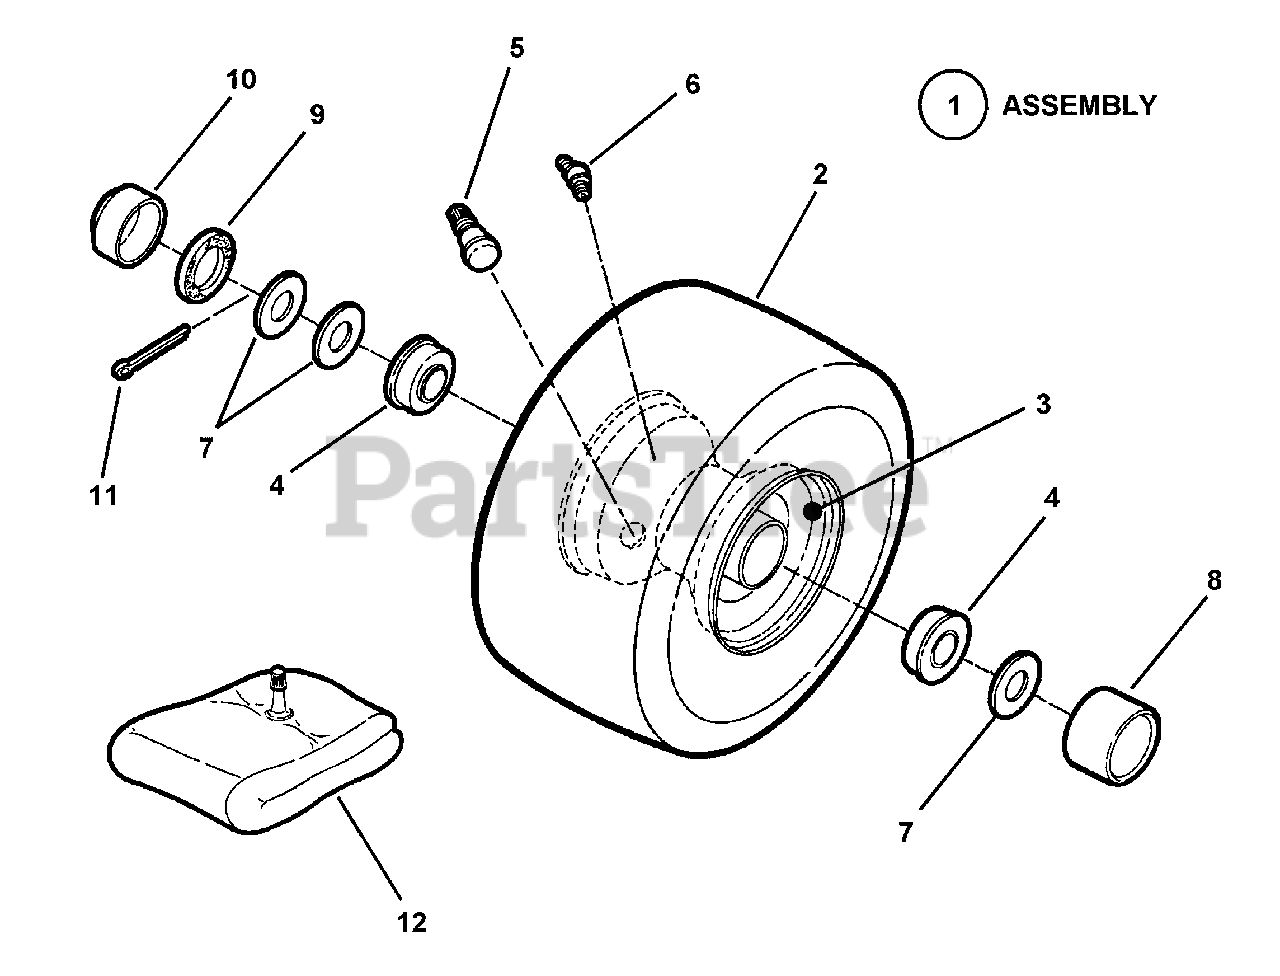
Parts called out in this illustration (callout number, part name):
1	ASSEMBLY, Front Tire & Rim (11.0")
2	TIRE, Pneumatic 11 x 4.00-4 (Kenda)
3	RIM
4	BEARING, Ball
5	VALVE, Air (Snap-In)
6	FITTING Lube
7	WASHER
8	CAP, Hub
9	SEAL, Felt
10	CAP, Dust
11	COTTER-PIN, 5/32 x 1"
12	TUBE, Inner
